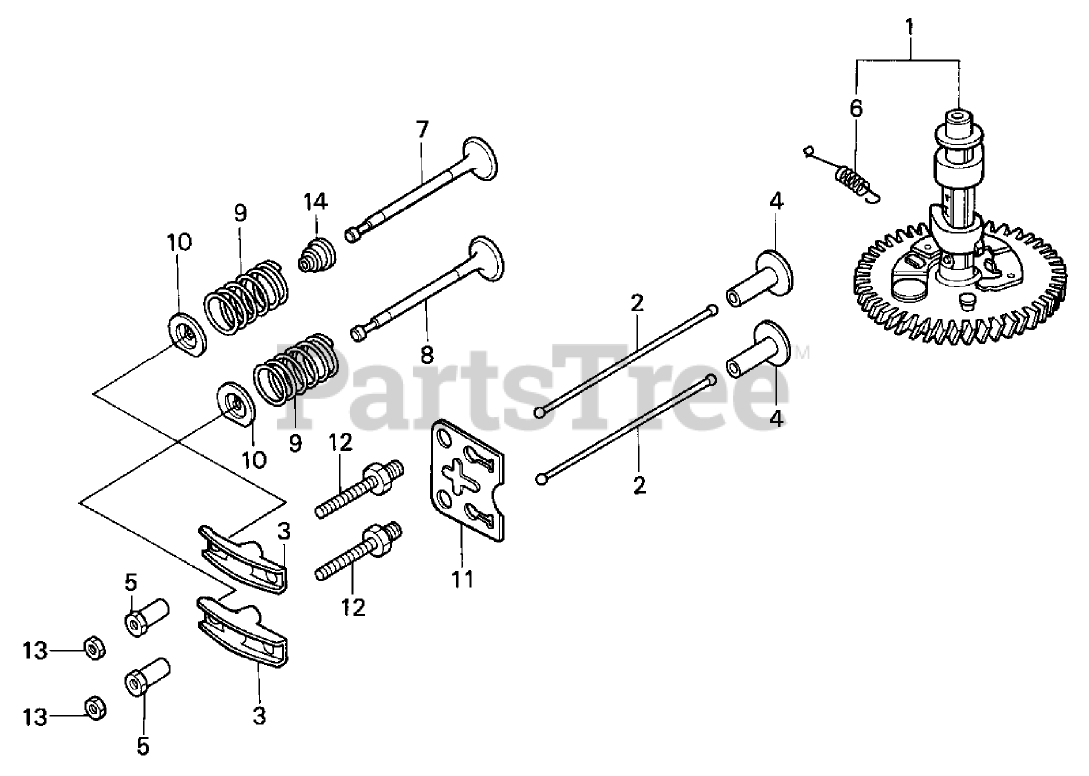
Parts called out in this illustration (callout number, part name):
1	CAMSHAFT ASM
2	Rod-Push
3	ARM-ROCKER, VALVE
4	Lifter-Valve
5	PIVOT-ARM, ROCKER
6	SPRING-RETURN, WEIGHT
7	VALVE-INTAKE
8	VALVE-EXHAUST
9	Spring-Valve
10	RETAINER-SPRING, VALVE (INTAKE)
11	Plate-GUIDE, Push Rod
12	BOLT-PIVOT (8 mm)
13	NUT-ADJUSTING, PIVOT
14	SEAL-STEM, VALVE
